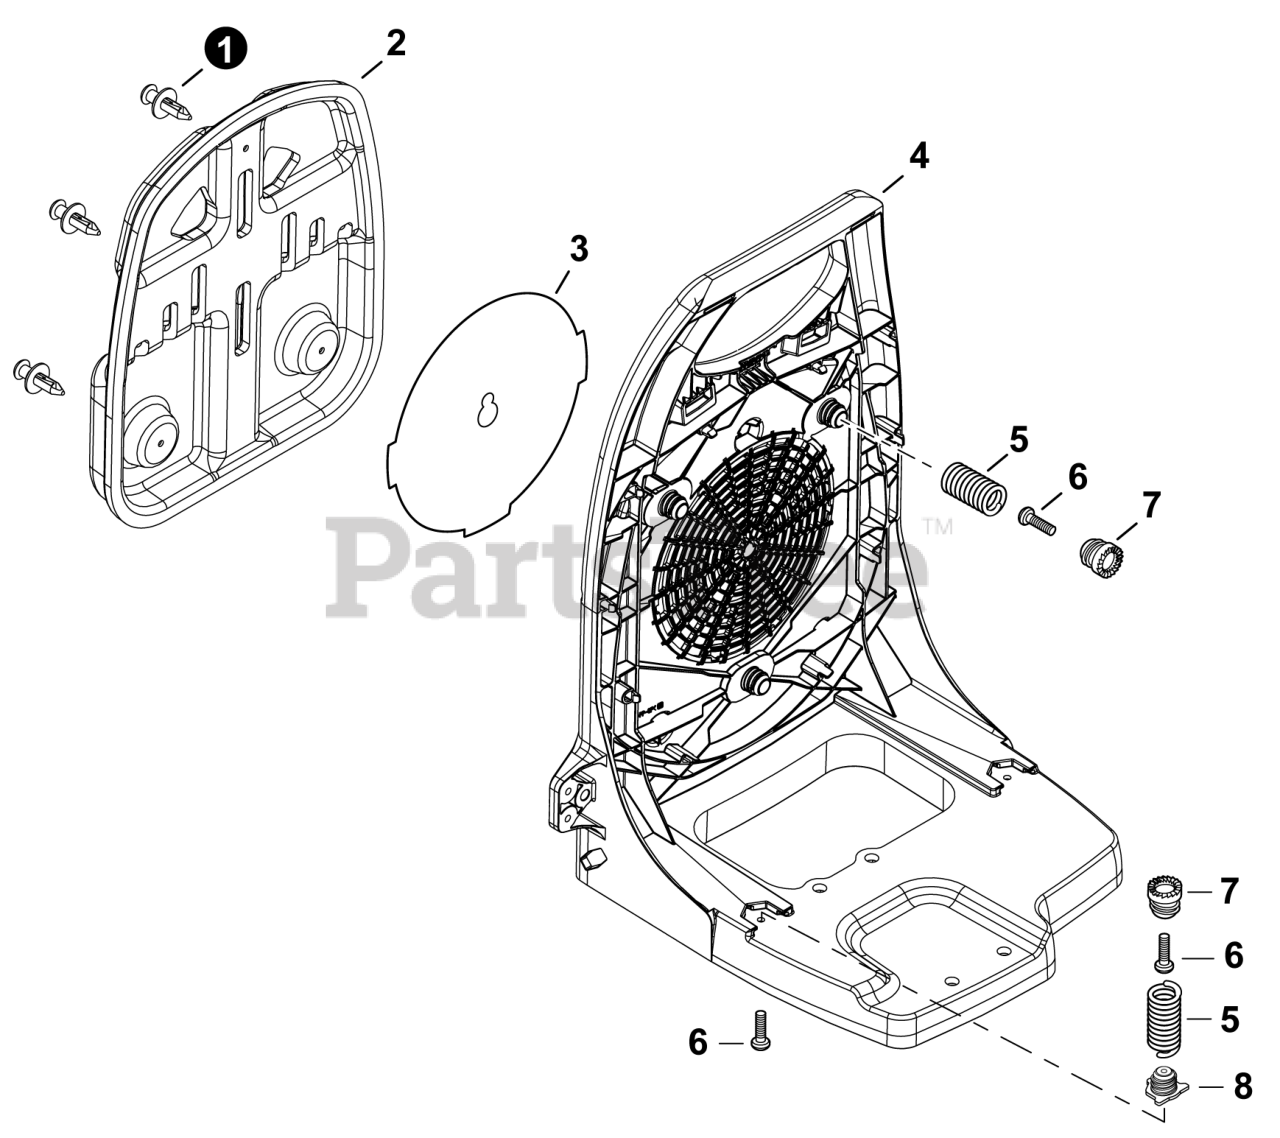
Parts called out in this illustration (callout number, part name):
2	CUSHION, BACKPACK
3	INSERT, COLD WEATHER
4	FRAME, BACKPACK
5	SPRING, COMPRESSION
6	BOLT, TORX 5x20
7	HOLDER, SPRING
8	HOLDER, SPRING
